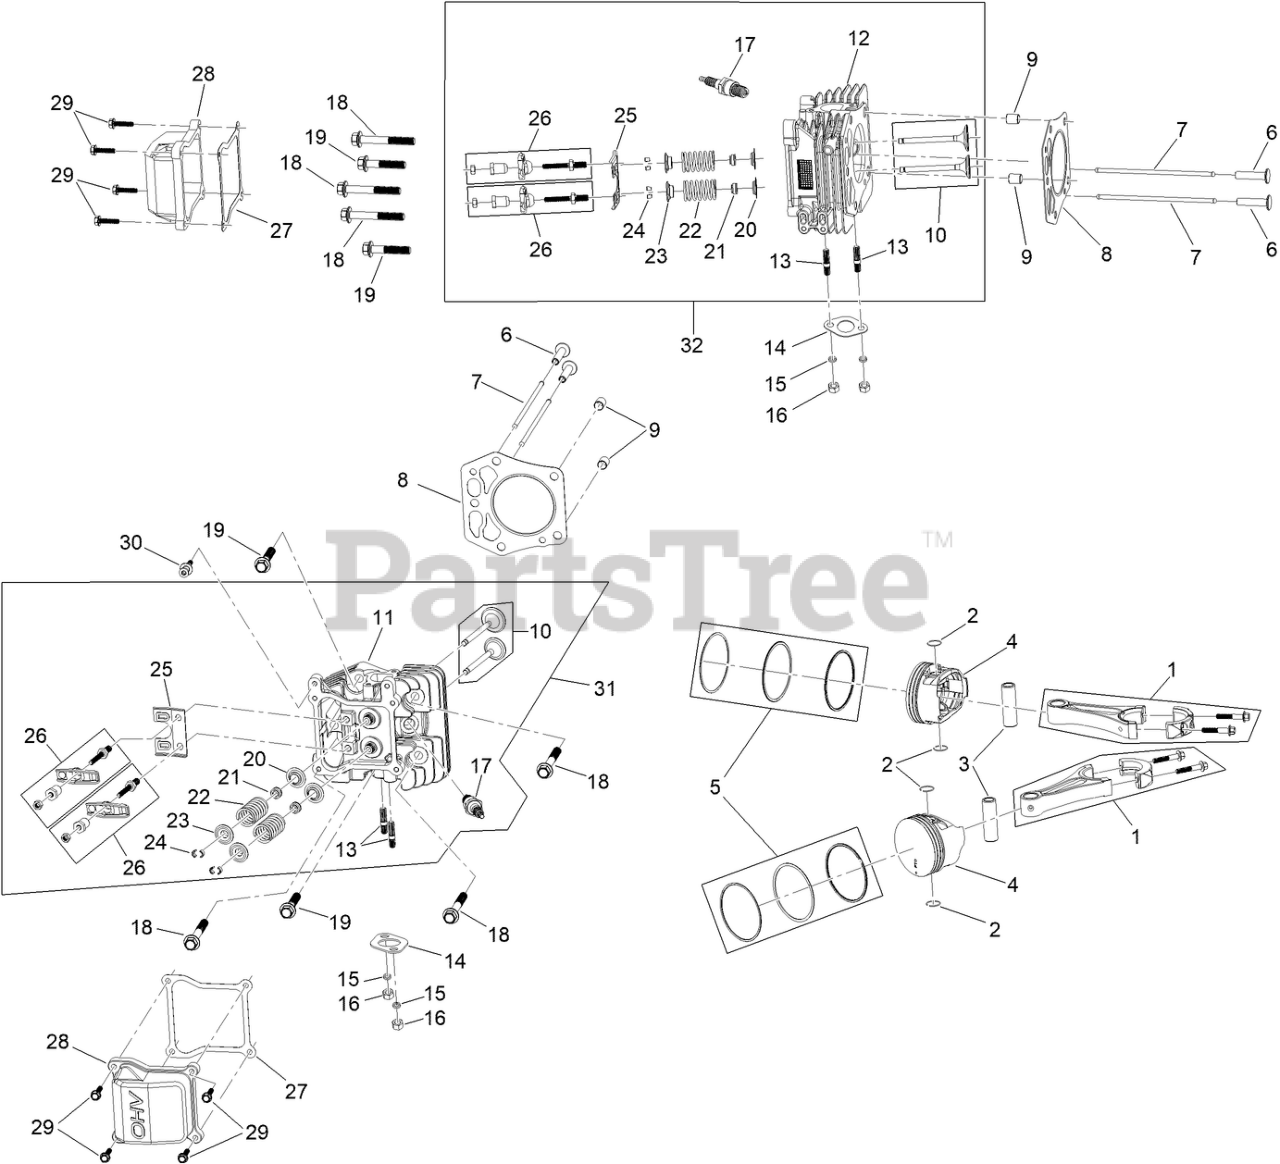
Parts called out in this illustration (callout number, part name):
1	CONNECTING ROD ASM
2	CLIP-PIN, PISTON
3	PIN-PISTON
4	PISTON
5	PISTON RING SET
6	LIFTER-VALVE
7	ROD-PUSH
8	GASKET-HEAD, CYLINDER
9	PIN-DOWEL
10	VALVE SET
11	HEAD-CYLINDER, RIGHT
12	HEAD-CYLINDER, LEFT
13	STUD-EXHAUST
14	GASKET-EXHAUST
15	WASHER-LOCK, SPLIT
16	NUT-HH
17	SPARK PLUG
18	SCREW-HWH
19	SCREW-HWH
20	SEAT-SPRING, VALVE
21	SEAL-STEM, VALVE
22	SPRING-VALVE
23	RETAINER-SPRING, VALVE
24	KEEPER-VALVE
25	PLATE-GUIDE, PUSH ROD
27	GASKET-VALVE COVER
28	COVER-VALVE
29	SCREW-HHF
30	SCREW-SHOULDER, HH
